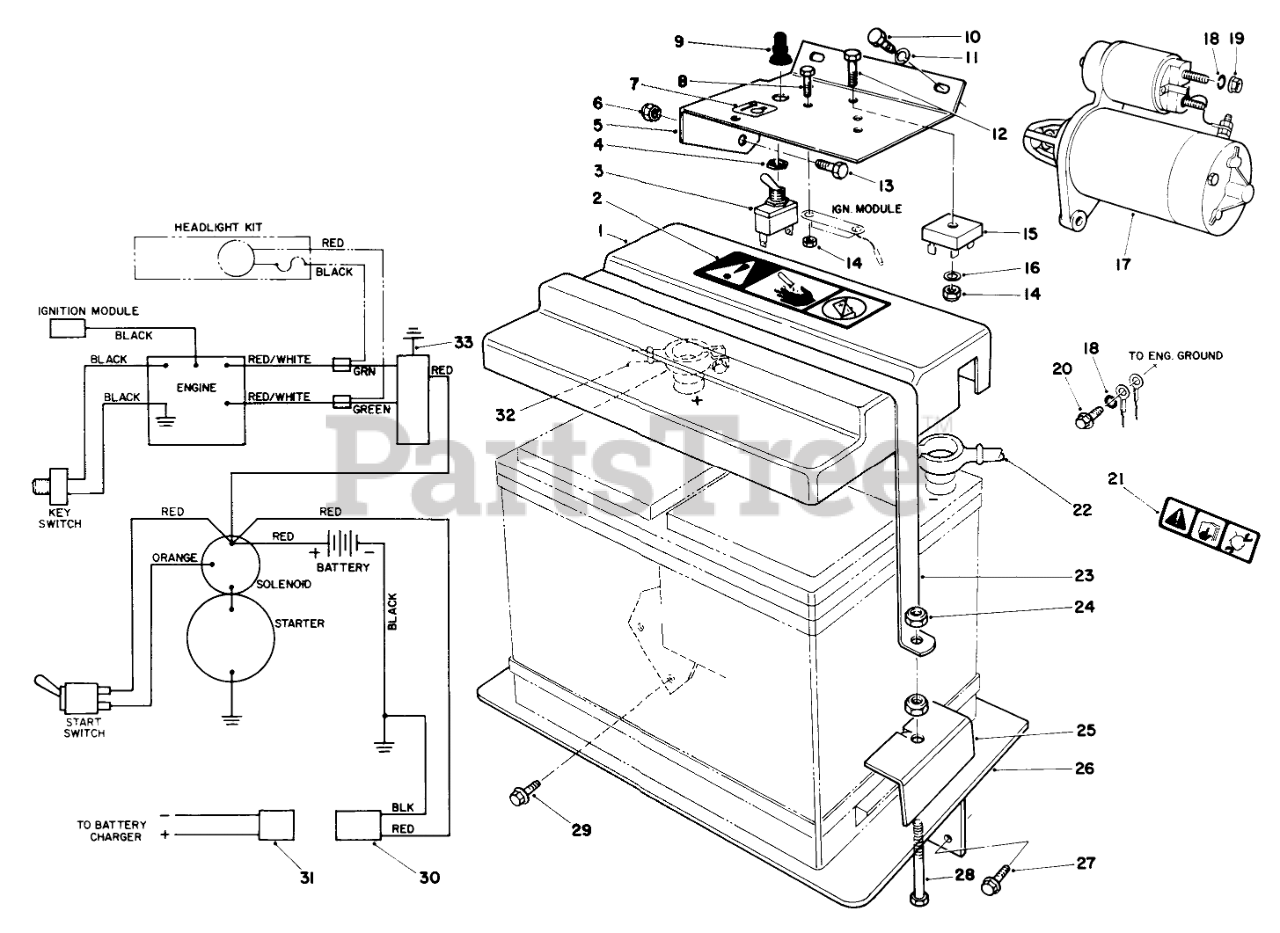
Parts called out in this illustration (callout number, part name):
1	BATTERY COVER
2	DECAL
3	Switch (Incl. Ref. #4 & 9)
4	NUT-LOCK
5	MOUNTING BRACKET
6	NUT-FLANGE, NI
7	DECAL - STARTER SWITCH
8	SCREW-SHH
9	BOOT-SWITCH
10	M6 X 1 HEX HD CAPSCRW
11	WASHER-SPRING
13	Screw-Cap Hex. Hd.
14	NUT-LOCK, NI
15	RECTIFIER-BRIDGE
16	WASHER-FLAT
17	12 Volt Starter Motor Assy.
18	WASHER-LOCK
19	NUT-FLANGE
20	SCREW-HHF
21	DECAL-WARNING
22	BATTERY CABLE
23	Strap Battery
24	NUT-LOCK, NI
25	BATTERY CLAMP
26	Plate-Battery
27	SCREW-HHF
28	SCREW-HH
29	SCREW-HHF
30	Charging Wire Assembly
31	FEMALE WIRE ASM
32	BATTERY CABLE
33	GROUND WIRE
